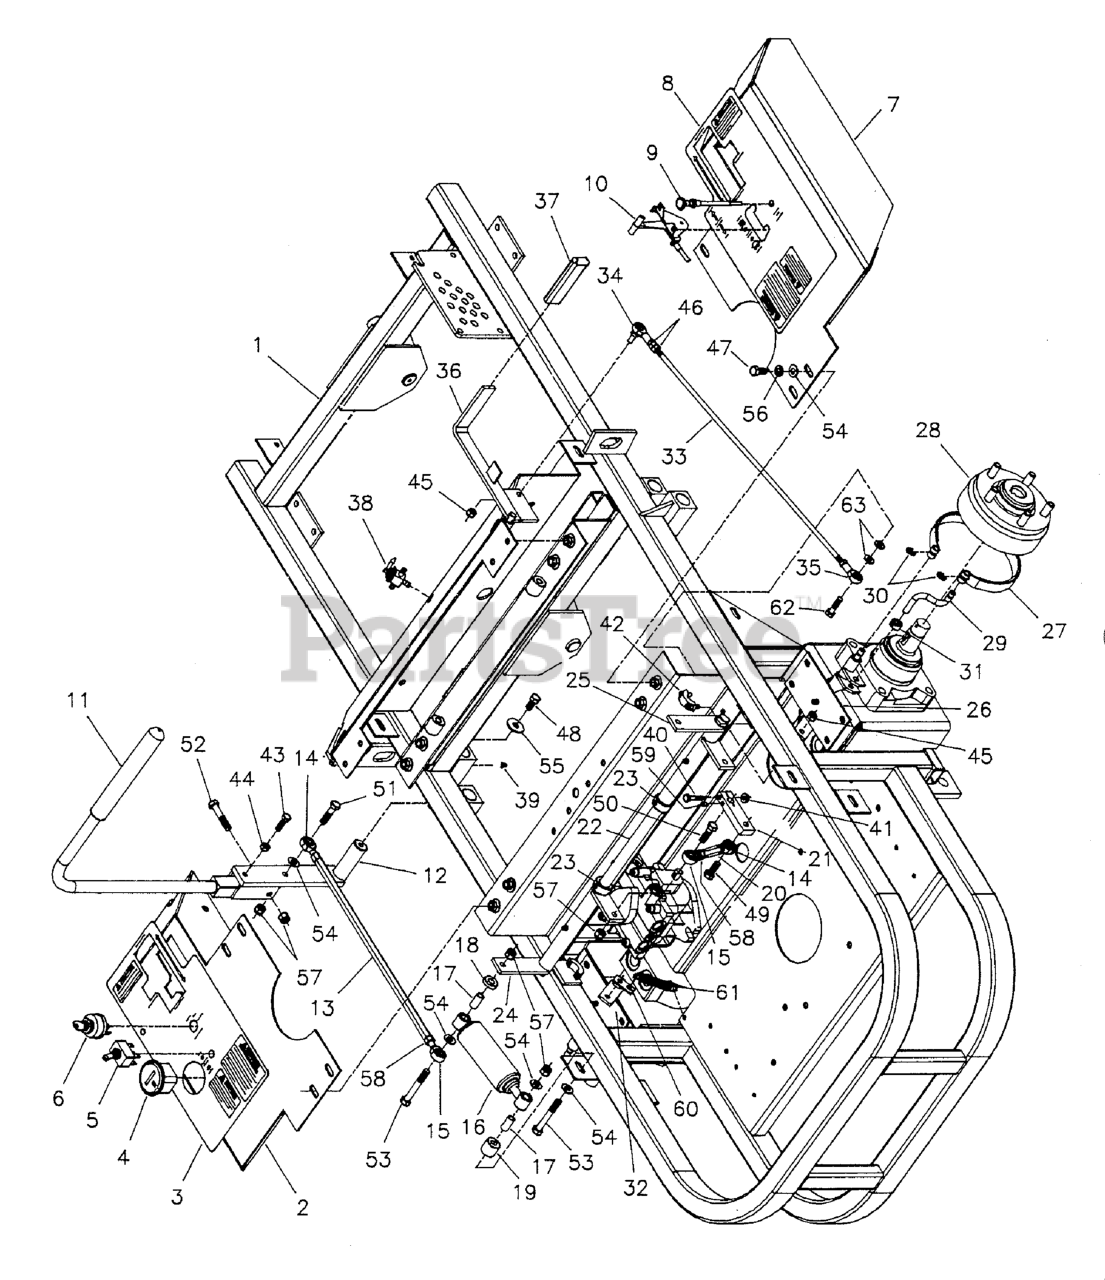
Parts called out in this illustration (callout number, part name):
1	FRAME, Main
2	PANEL, Control, Left
3	DECAL, Control Panel, Left
4	HOUR METER
5	SWITCH, Electric Clutch
6	SWITCH, IGNITION, 6 POST
7	PANEL, Control, Right
8	DECAL, Control Panel, Right
9	CABLE, Choke Control, 57"
10	CABLE, Throttle, 38"
11	HYDRO CONTROL HANDLE ASSEMBLY
12	LEVER, Control
13	ROD, Hydro Control
14	BALL JOINT, 3/8-24 LH Male
15	BALL JOINT, 3/8-24 Male
16	DAMPENER
17	SPACER, .38 x .50 x 1.00
18	SPACER, .39 x 1.00 x .25
19	SPACER, .39 X 1.00 X .87
20	LINK, Control Arm
21	ARM, Pump Control
22	SHAFT, Control Pivot
23	COLLAR, 3/4" Set
24	CONTROL, Hydro, Left
25	CONTROL, Hydro, Right
26	BRAKE PIVOT, Right
27	BRAKE BAND
28	HUB, Studded w/Brake Drum
29	LINK, Brake Band
30	RING, E-Retaining
31	COLLAR, 3/8" Set
32	BRAKE PIVOT, Left
33	ROD, Brake Actuator
34	BALL JOINT 5/16-24 LH FEMALE W/STUD, BR
35	BALL JOINT, 5/16-24 LH FEMALE W/STUD, BR
36	PANEL, Brake
37	GRIP, FOAM, 1/4 X 1 X 4.1
38	VALVE, Fuel Shut Off
39	GREASE FITTING
40	BOLT, 1/4-20 X 1-1/2
41	NUT, 1/4-20 HEX SERR. FLANGE
42	COLLAR, 3/4" Double Split
43	BOLT, 5/16-18 X 1 GD5 YZ
44	NUT, 5/16-18 HEX
45	NUT, 5/16-18 Hex Nylon Lock
46	NUT, 5/16-24 Hex
47	BOLT, 3/8-16 X 3/4" GD5 CZ
48	BOLT, 3/8-16 X 3/4, PLT W/PATCH
49	BOLT, 3/8-16 X 1" GD5 CZ
50	BOLT, 3/8-16 X 1-1/4" GD5 CZ
51	BOLT, 3/8-16 X 1-1/2" GD5 CZ
52	BOLT, 3/8-16 X 2, GD5, CZ
53	BOLT, 3/8-16 X 2-3/4" GD5 CZ
54	WASHER, 3/8 SAE
55	WASHER, 3/8" Fender
56	WASHER, 3/8" Lock
57	NUT, 3/8-16 HEX NYLON LOCK
58	NUT, 3/8-24 Hex
59	SET SCREW, 1/4-20 x 3/8" Cone Point
60	SPACER, Spring
61	SPRING, Extension
62	BOLT, 5/16-18 x 1-1/4
63	WASHER, 5/16" SAE
